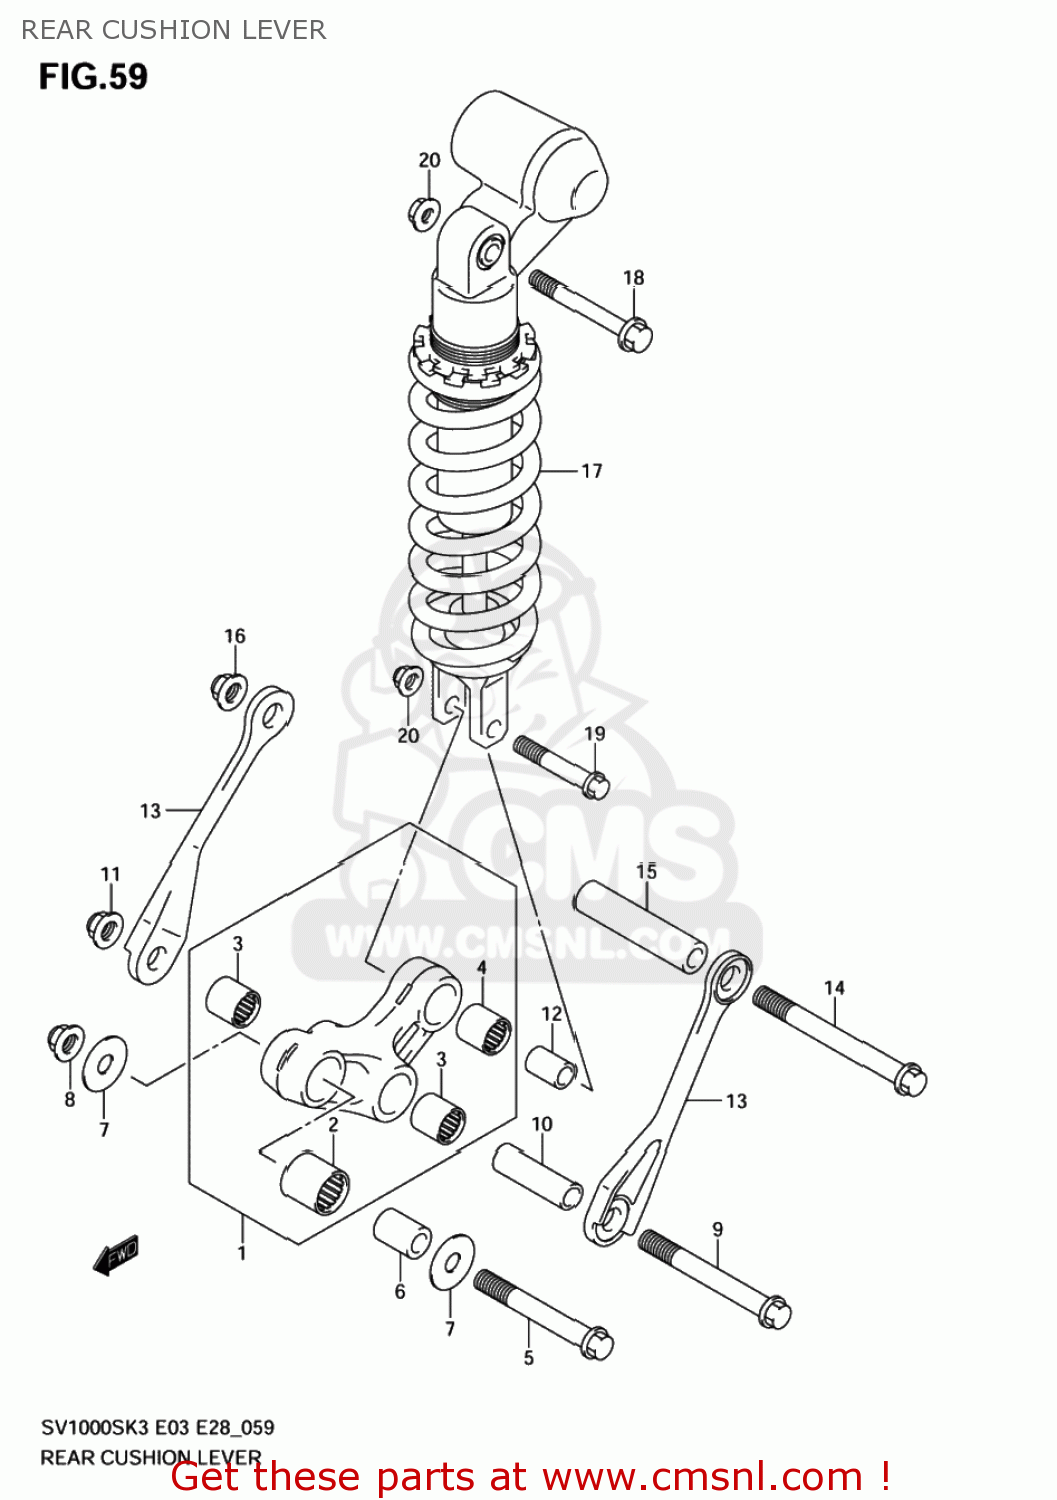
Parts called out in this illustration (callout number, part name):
1	HEVELSET
2	BEARING(20X27X30)
3	BEARING(17X24X20)
4	BEARING(17X24X26)
5	BOLT,RR CUSHION LEVER FR
6	SPACER,RR CUSHION LEVER FR
7	WASHER(12X34X1)
8	NUT
9	BOLT,RR CUSHION LEVER CTR
10	SPACER,RR CUSHION LEVER CTR
11	NUT
12	SPACER,RR CUSHION LEVER
13	ROD,RR CUSHION LEVER
14	BOLT,RR CUSHION ROD
15	SPACER(12X17X85)
16	NUT
17	ABSORBER ASSY,RR SHOCK(WHITE)
18	BOLT(10X70)
19	BOLT(10X55)
20	NUT
